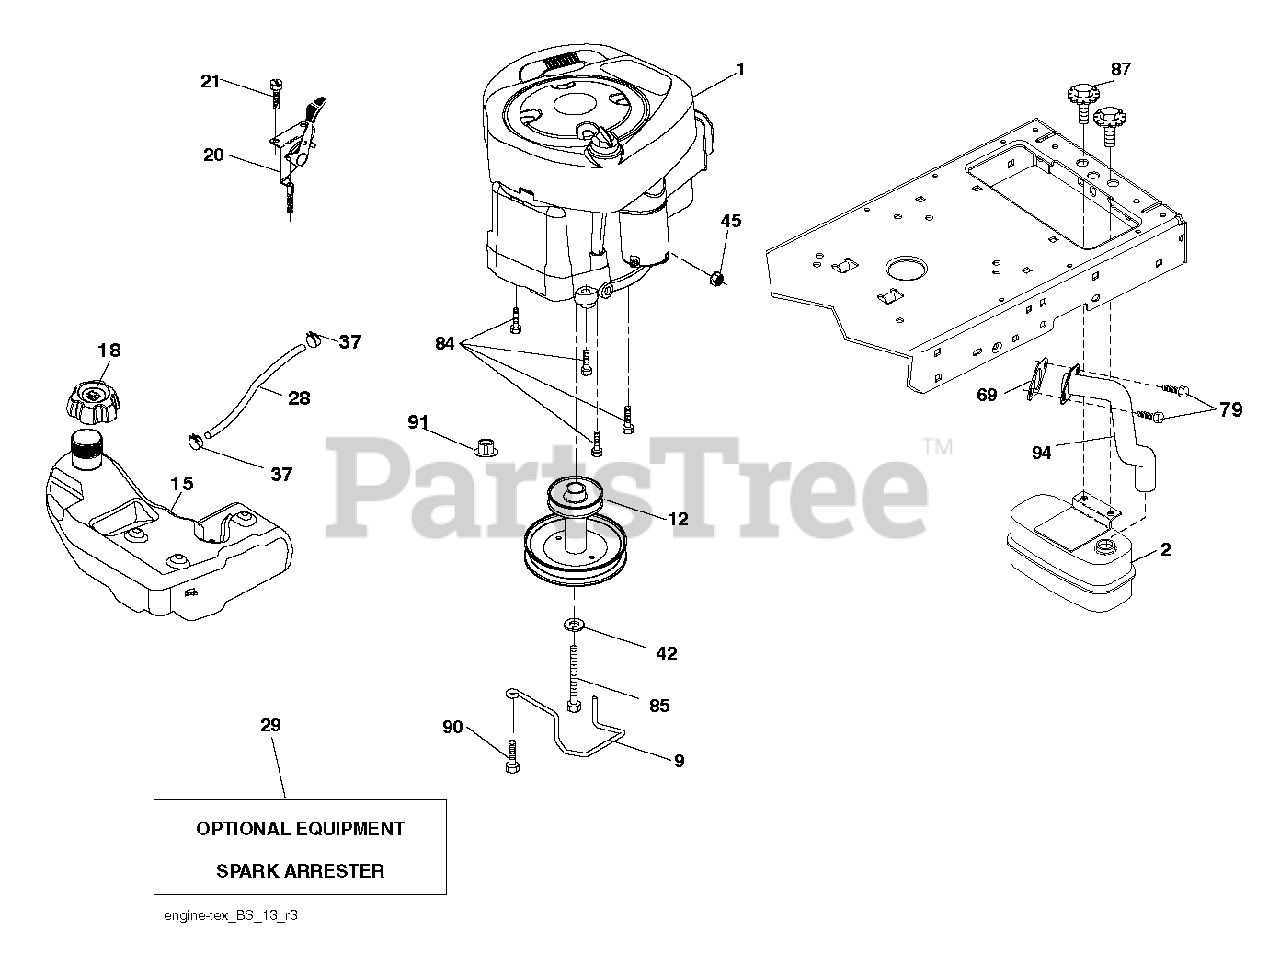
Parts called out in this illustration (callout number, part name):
2	MUFFLER.SINGLE.CYL.KOHL/B&S
9	KEEPER.BELT.ENGINE.4.2
12	PULLEY ENGINE
15	TANK.ASSY.3.GAL.EPA
18	CAP.ASM.FL.RITCH.3"E10.SYM.498
20	CONTROL.TH/CK.COBRA.KO
21	SCREW.#10 X 0.750.BOS
28	LINE.FUEL.20"FRONT.EMI
29	KIT.SPARK ARRESTOR 794945 B&S
37	HOSE CLAMP
42	LOCKWASHER
45	NUT
69	REPL BY 532 27 22-93
79	SCREW.SOCKET HD.5/16-1
84	SCREW.3/8-16
85	BOLT HEX 7/16-20X4-1/4"
87	Bolt, 5/16-18 X 1-3/4
90	SCREW 3/8-16X1
91	BUSHING.1.375OD
94	EXHAUST.TUBE.B&S.
